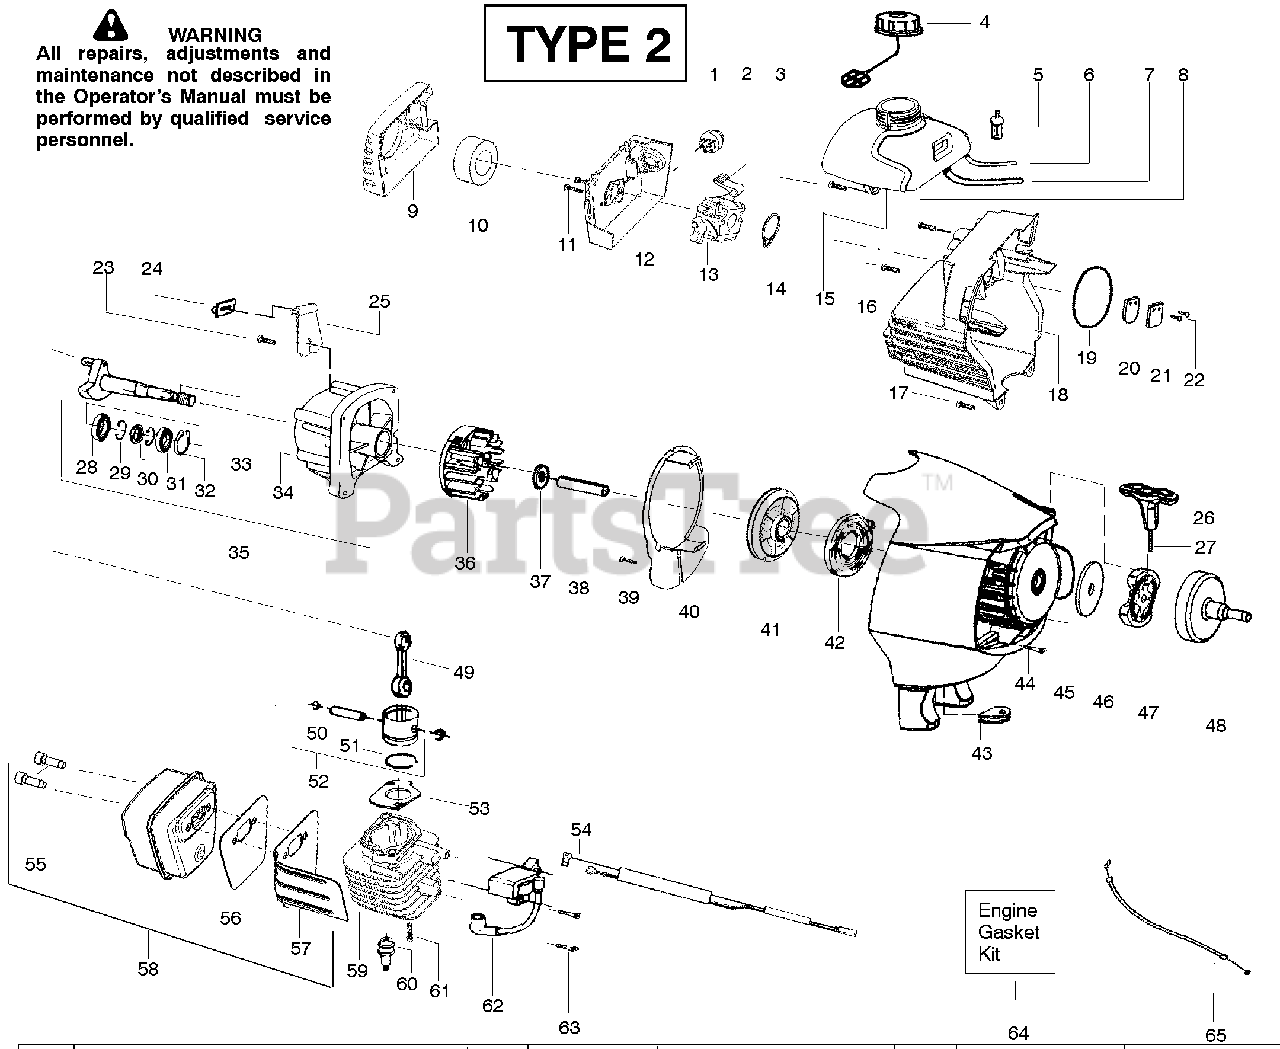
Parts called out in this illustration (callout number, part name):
2	Kit-Choke Lever
4	Cap-Fuel w/ret.
5	Assy-Fuel pickup
6	Kit-Fuel line
7	Kit-Fuel/Purge line
9	Cover-Air box
13	Kit-Carb assy. (C1U-W32)
14	Seal-Carb.(kit)
15	Assy-Fuel Tank
16	Screw-Crankcase
18	Assy-Rear Shroud
19	O-ring-Shroud (kit)
22	Screw-Reed stop
23	Screw-Retainer
24	Isolator-Tank
26	Handle-Starter
28	Bearing-Inner
31	Bearing-Outer
32	Ret.-Crankshaft
33	Assy-Crankshaft
34	Assy-Crankcase
35	Assy-C'case/C'shaf
36	Assy-Flywheel
42	Spring-Starter
44	Screw-F/hsg.
45	Assy-Fan Housing
46	Washer-Clutch
48	Assy-Drum/Adapter
49	Assy-Conn. Rod
50	Ret.-Piston pin
52	Kit-Piston
53	Gasket-Cylinder(kit)
54	Assy-Leadwire
55	Bolt-Muffler 1/4"-20
56	Gasket-Muffler (kit)
58	Kit-Muffler
60	Plug-Spark(RCJ-6Y)
61	Bolt-Cyl. 1/4"-20
62	Module-Ignition
64	Kit-Gasket/Seal
65	Assy-Throttle cable
